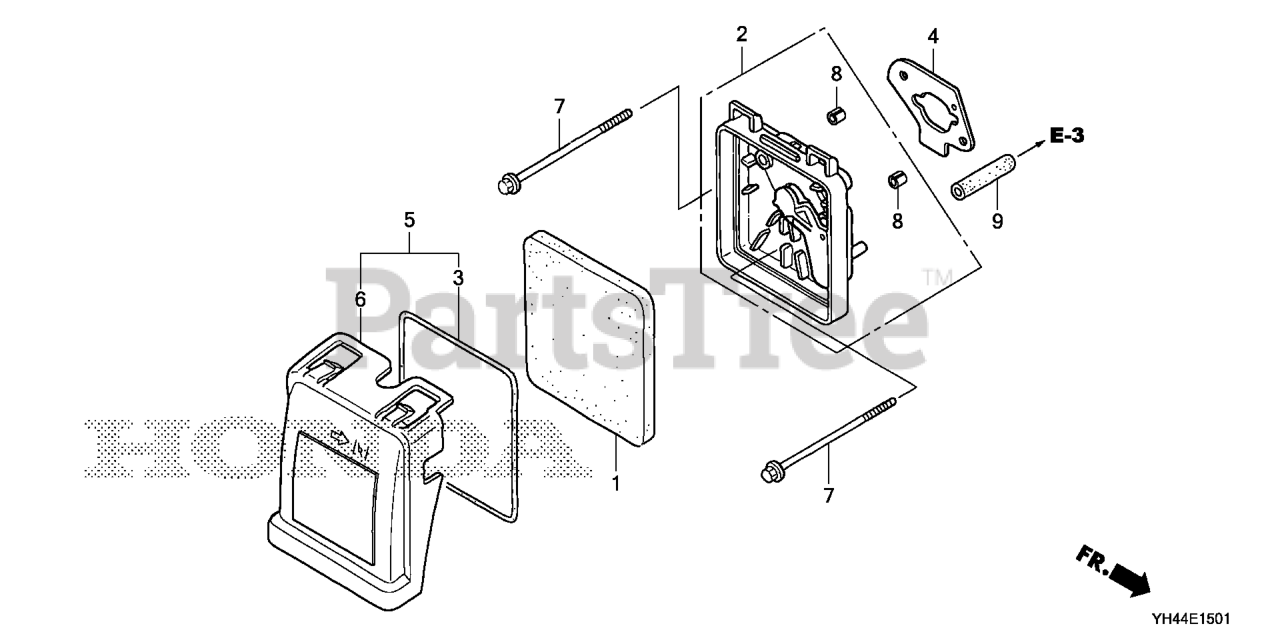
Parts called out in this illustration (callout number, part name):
1	ELEMENT, AIR CLEANER
2	HOUSING, AIR CLEANER
3	SEAL, AIR CLEANER
4	GASKET, AIR CLEANER
5	COVER, AIR CLEANER
6	COVER, AIR CLEANER
7	BOLT, FLANGE (5X75)
8	COLLAR, AIR CLEANER
9	BULK HOSE, VACUUM (7X3000) (7X550)
